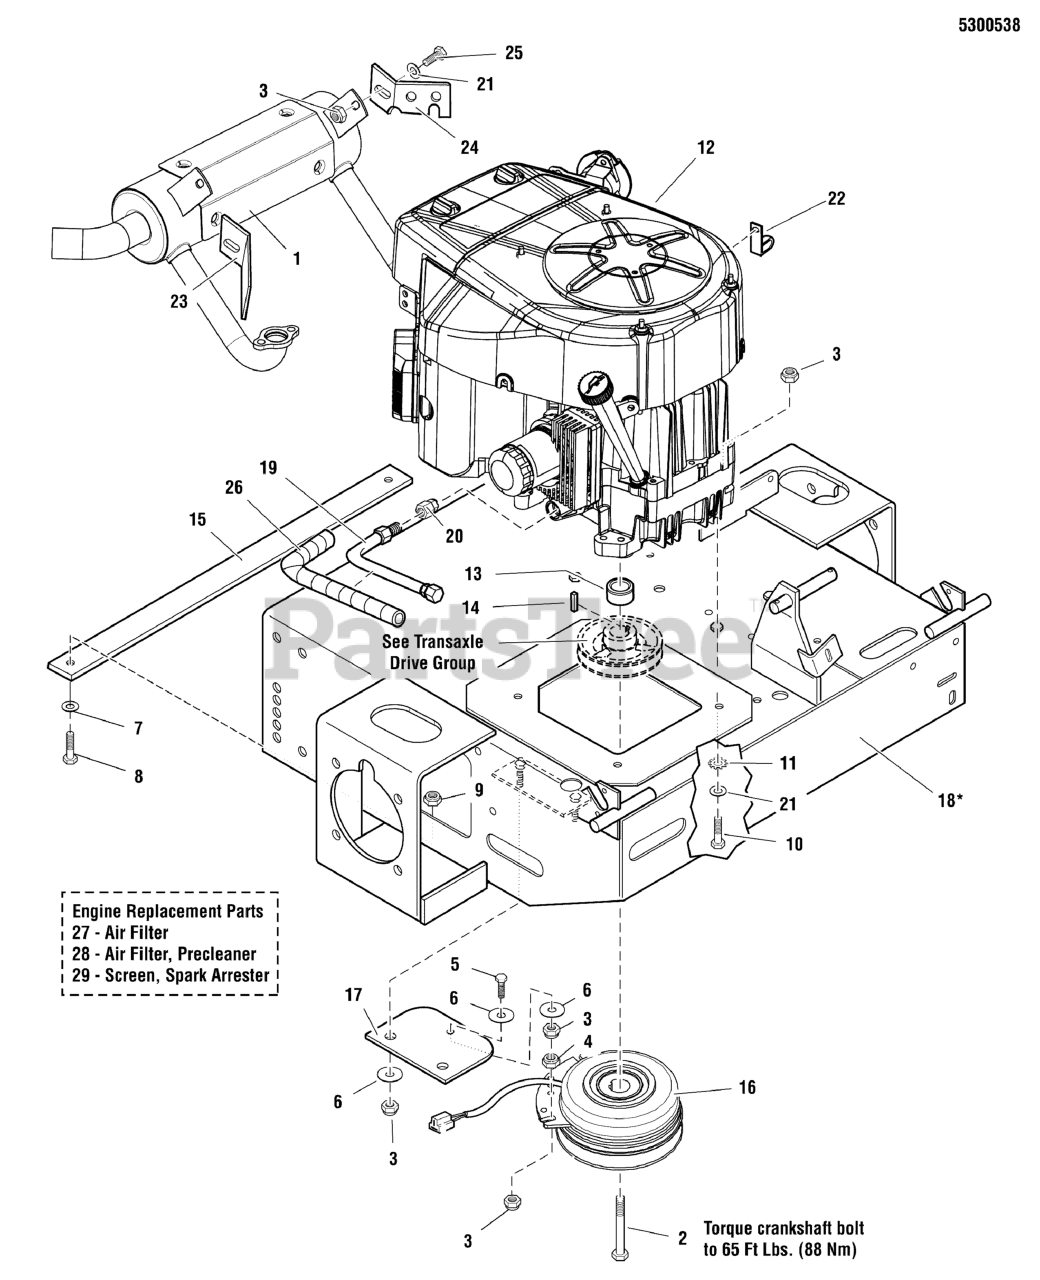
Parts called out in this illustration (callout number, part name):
1	MUFFLER, KAWASAKI
2	BOLT, CRANKSHAFT, 7/16"X2-1/2
3	NUT, 5/16-18 HEX NYLOCK FLANGE
4	NUT, 5/16-18 HEX SERRATED FLANGE (LARGE)
5	BOLT, 5/16-18 X 2-1/4 TFL, GD5 YZ
6	WASHER, .34 X 1.25 X 10 GA
7	WASHER, 1/2" GD9 YZ
8	BOLT, 1/2-20 X 1-1/4" GD5 CZ
9	NUT, Hex, Nylon Lock, 1/2-20
10	BOLT, 5/16-18 X 1-3/4" GD5 YZ
11	WASHER, 5/16" INT. TOOTH LOCK
13	SPACER, 1.13 X 1.75 X .97
14	KEY, 1/4" SQ. X 1.25
15	TIE BAR - RED
16	** CLUTCH, 5218-134, WARNER
17	CLUTCH ANCHOR PAD
19	HOSE-OIL DRAIN
20	ADAPTER, OIL DRAIN
21	WASHER, 5/16" SAE
22	CLAMP, VINYL INSULATED
23	MUFFLER BRACKET, OIL FILTER SIDE - RED
24	MUFFLER BRACKET, FUEL PUMP SIDE - RED
25	BOLT, 5/16-18 X 1"
26	WIRE LOOM, 3/4" ID, 7" LONG
27	AIR FILTER, KAWI 11013-7027
28	PRECLEANER, KAWI 11013-7009
29	SCREEN, SPARK ARRESTER
